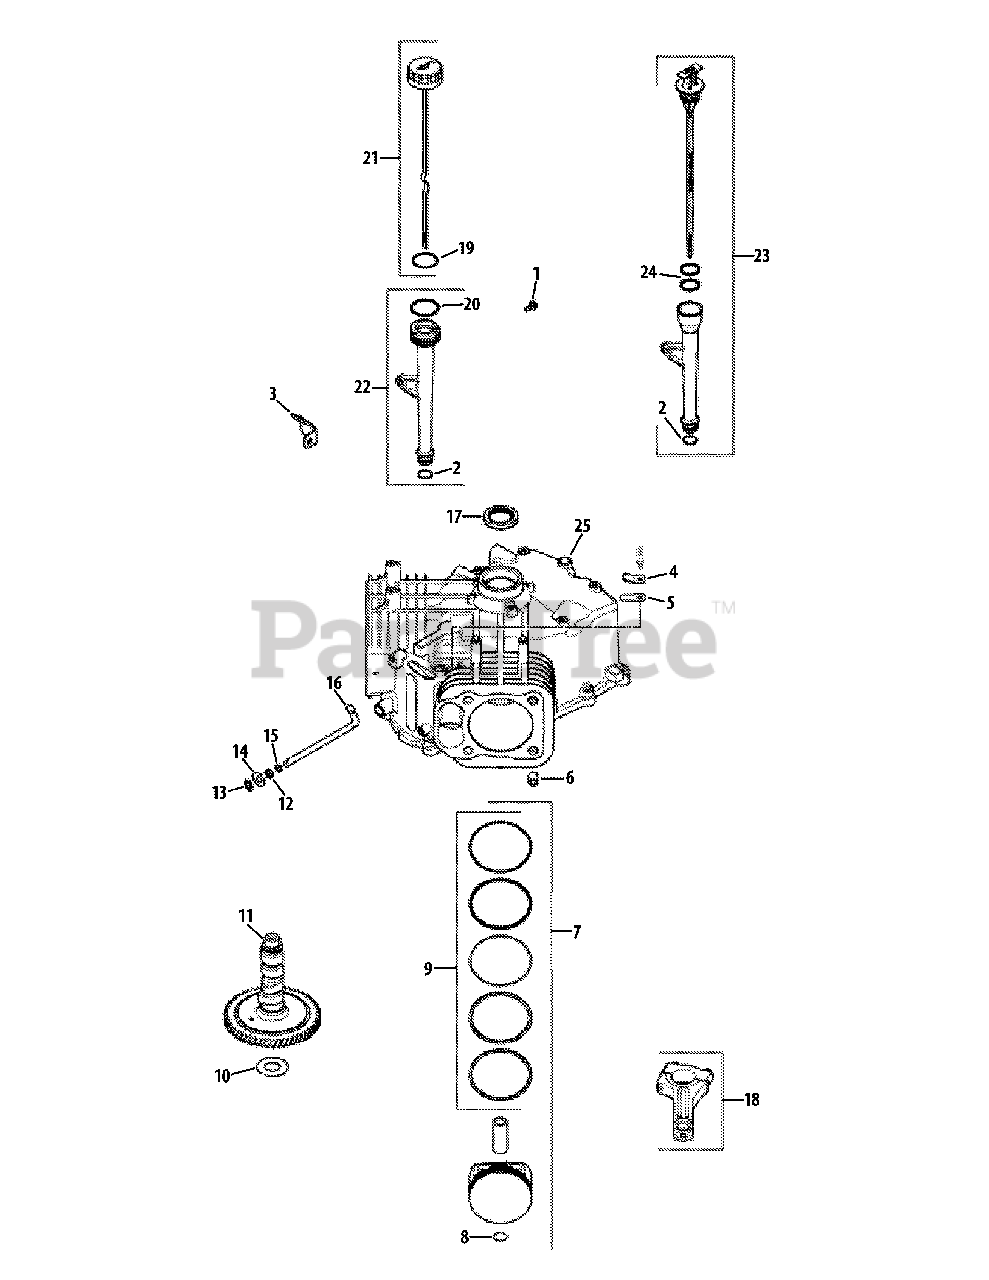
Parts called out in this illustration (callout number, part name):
1	Flange Screw, M5 x .8 x 13
2	Lower Oil Fill Tube O-Ring
3	Oil Fill Tube Bracket
4	Breather Reed Retainer
5	Breather Reed
7	Piston Kit w/ Ring Set, 83mm (STD) (Inc. #8 & 9)
7	Piston Kit w/ Ring Set, 83mm (.25) (Inc. #8 & 9)
7	Piston Kit w/ Ring Set, 83mm (.08) (Inc. #8 & 9)
8	Piston Pin Retainer
9	Ring Set, .08
9	Ring Set, STD
9	Ring Set, .25
10	Camshaft Shim, .028 (White)
10	Camshaft Shim, .03 (Blue)
10	Camshaft Shim, .032 (Red)
10	Camshaft Shim, .034 (Yellow)
10	Camshaft Shim, .036 (Green)
10	Camshaft Shim, .038 (Gray)
10	Camshaft Shim, .04 (Black)
11	Camshaft Kit (Inc. KH-25-357-14-S)
12	Governor Cross Shaft Seal
13	Ring Retainer
14	Flat Washer, 9mm
15	Flat Washer, 11.32
16	Governor Cross Shaft
17	Oil Seal, 1.78 x 1.26
18	Connecting Rod (STD)
19	Dipstick O-Ring
20	Upper Oil Fill Tube O-Ring
21	Dipstick Assembly (Inc. #19)
22	Tube Assembly (Inc. #2, 19 & KH-12-123-04-S)
23	Dipstick & Tube Kit
24	O-Ring
25	Crankcase (Use Short Block)
